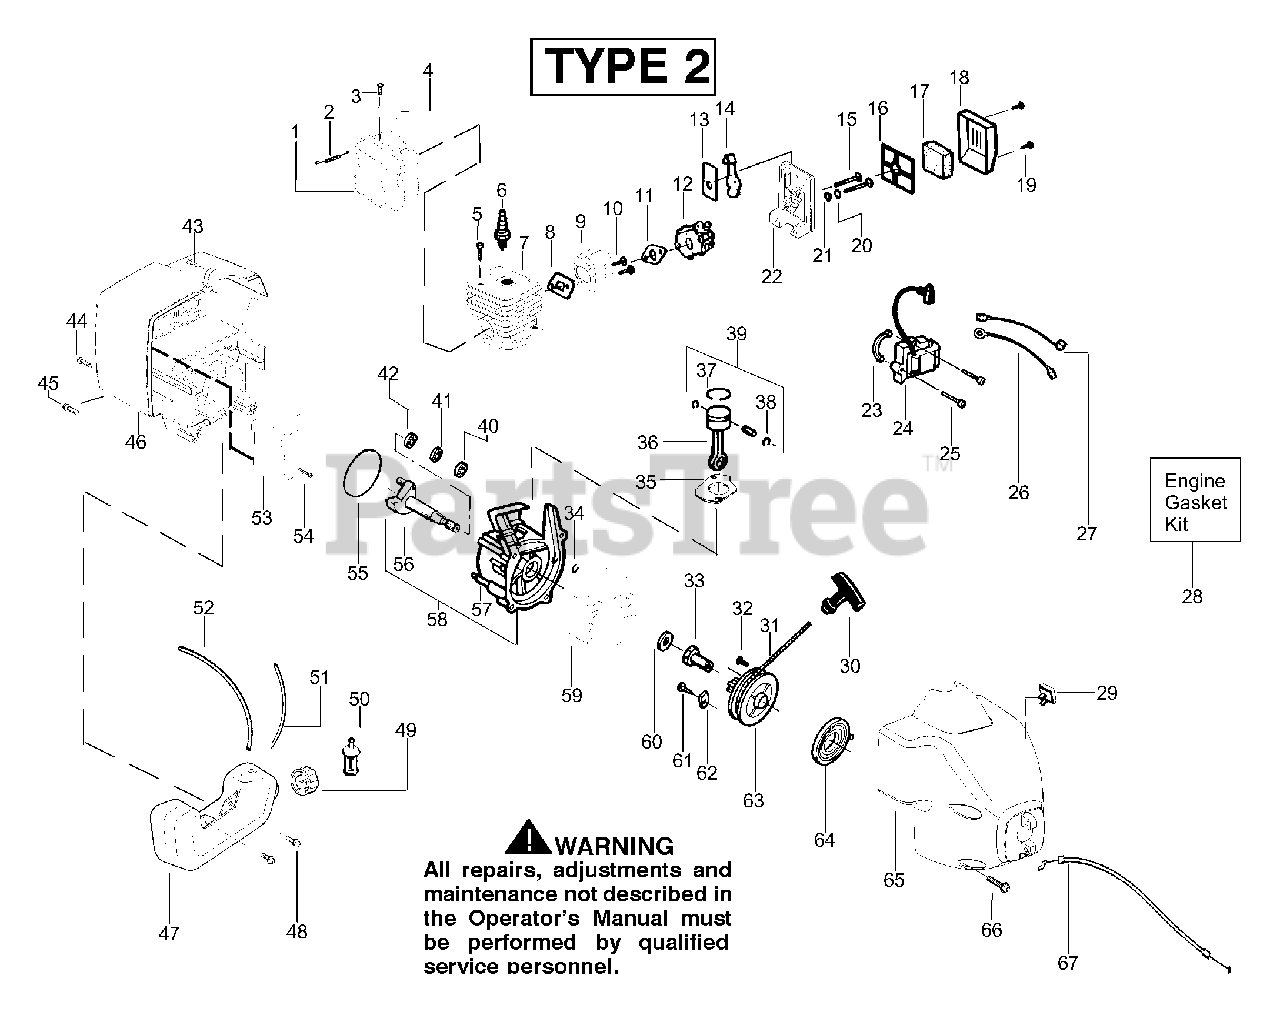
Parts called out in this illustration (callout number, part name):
1	Kit-Muffler
2	Muffler Spring
3	Screw-screen
4	Screen-Spark Arrestor
5	Screw-Cylinder
6	Spark Plug (RCJ-6Y)
7	Kit-Cylinder
8	Gasket-Cylinder/Carb.
9	Carb. Adapter
10	Screw-Carb Adptr.
11	Gasket-Carb.
12	Kit-Carb. Ass'y.
13	Choke Plate
14	Choke Shutter
15	Screw-Carburetor
16	Filter Support Plate
17	Air FIlter Foam
18	Air Filter Cover
19	Screw-Air Box
20	Choke Spacer
23	Spacer-Ignit. Module
24	Ignition Module
25	Screw-Ignit. Module
26	Assy-Ground Wire
27	Assy-Lead Wire
28	Kit-Engine Gasket
29	Kit-Switch-Off/On
30	Handle-Starter
31	Kit-Rope
33	Coupling-Drive
34	Ret. Ring/C'shaft
35	Gasket-Cylinder
36	Assy-Connecting Rod
37	Ring-Piston
38	Retainer-Piston Pin
39	Kit-Piston
40	Bearing-Outer
41	Seal-C'case
42	Bearing-Inner
43	Screw-Shd/Fan Hsg
44	Screw
46	Rear Shroud
47	Assy-Fuel Tank
48	Retainer-Tank
49	Assy-Fuel Cap
50	Assy-Fuel Pickup
51	Fuel Line (Small)
52	Fuel Line (Large)
53	Shield-Heat
54	Screw-Heat Shield
55	O-ring-C'case
56	Assy-Crankshaft
57	Assy-Crankcase
58	Assy-c'case/c'shaft
59	Assy-Flywheel
60	Washer-Flat
61	Screw-Pulley
62	Retainer-Pulley
63	Kit-Starter Pulley
64	Spring-Starter
65	Assy.-Fan Hsg.
66	Screw
67	Assy-Throttle Cable
